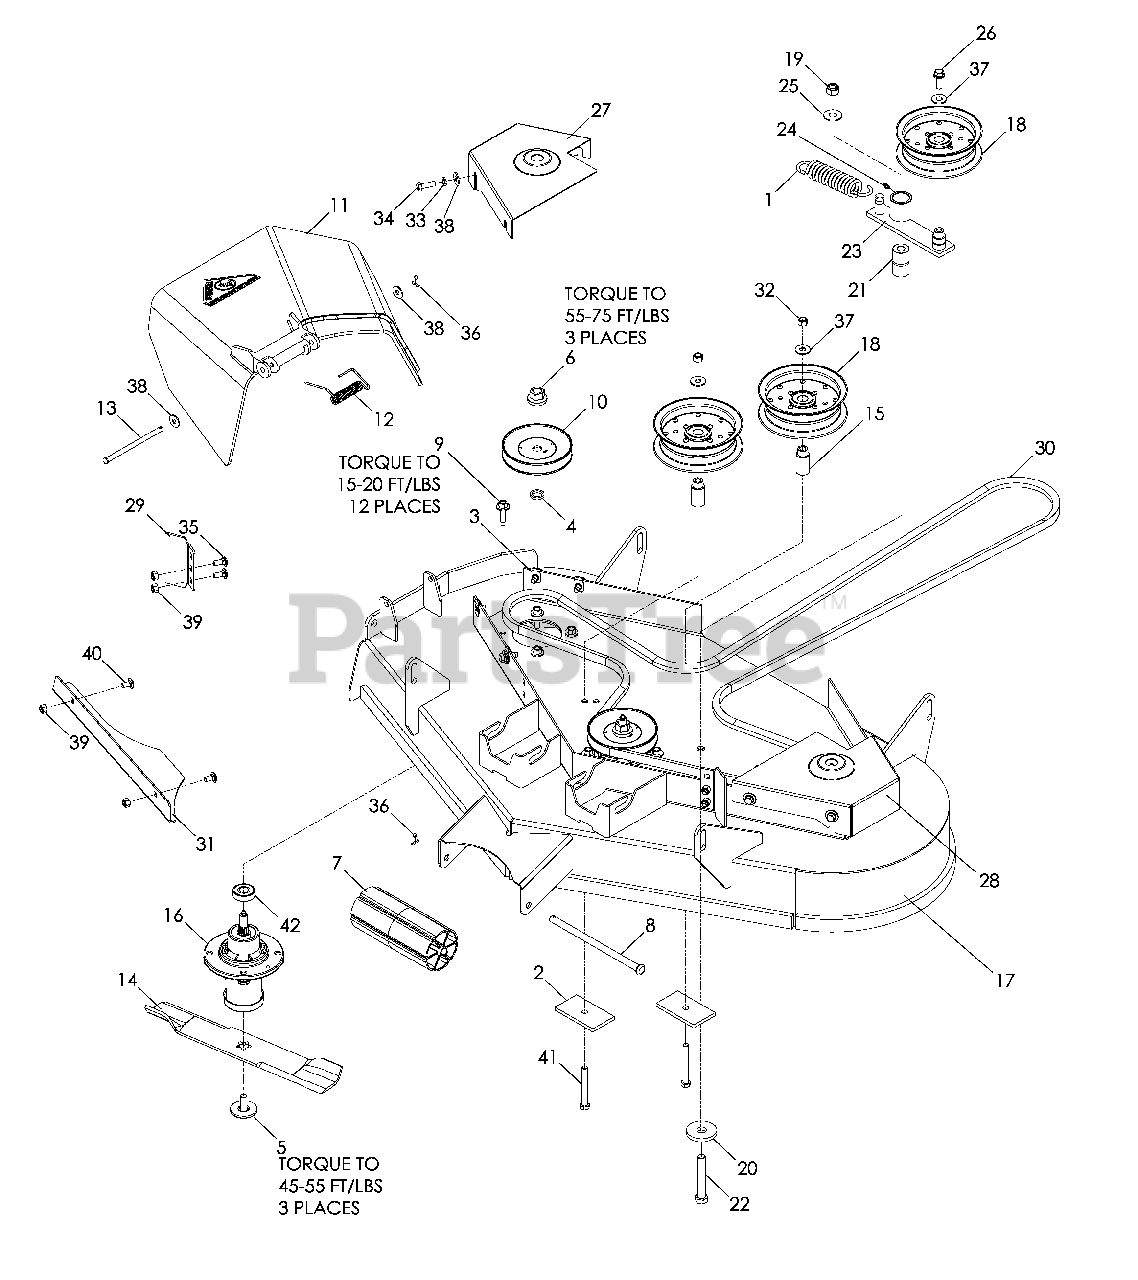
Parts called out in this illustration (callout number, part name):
1	SPRING, EXTENSION
2	PAD
3	NUT 5/16-18 RETAINER-U
4	WASHER, SPACER
5	BOLT 7/16 SPEC
6	NUT 9/16 TOP CNTRLOCK
7	ROLLER, NOSE
8	ROD, ROLLER, NARROW
9	SCREW 5/16-18 x 13/8 WSH HD
10	PULLEY, MANDREL
11	CHUTE, DISCHARGE
12	SPRING, TORSION
13	PIN-CLEVIS, 5/16 DIA x 5.19
14	BLADE, 14.625"
15	BUSHING, IDLER
16	HOUSING ASSEMBLY
17	DECK W/DECALS
18	PULLEY, IDLER NYLON
19	NUT ½-13 NYLOC
20	WASHER .65 SUPPORT
21	BUSHING, PIVOT
22	HCS ½-13 x 3¼
23	ARM, IDLER
24	ZERK, STRAIGHT ¼-28
25	WASHER 9/16
26	HCS 3/8-16 x 1 WHIZLK
27	BELTSHIELD, RIGHT
28	BELTSHIELD, LEFT
31	PLATE, CONFINEMENT
32	NUT 3/8-16 NYLOC
33	LOCKWASHER 5/16
34	HCS 5/16-18 x 1
35	RHSNB 5/16-18 x ¾
36	PIN, COTTER 1/8 x ¾
37	WASHER 3/8
38	WASHER 5/16
39	NUT 5/16-18 NYLOC
40	RHSNB 5/16-18 x 5/8
41	HCS 3/8-16 x 3
42	BEARING, BALL
